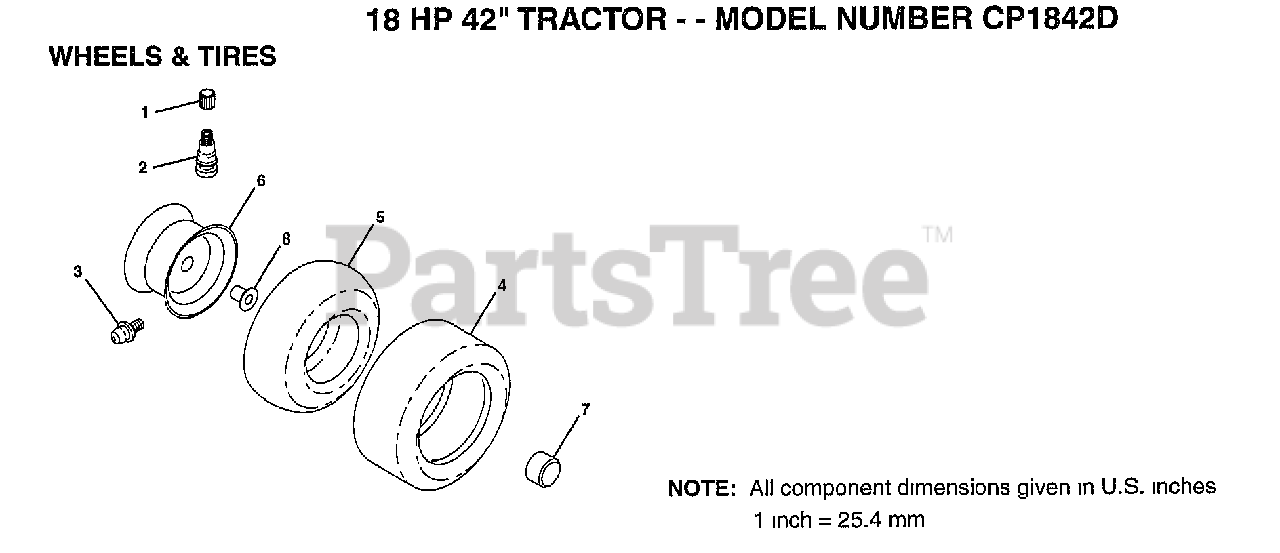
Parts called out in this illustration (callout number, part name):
1	VALVE CAP
2	VALVE STEM LT
3	FITTING LT
4	TIRE.20X8-8
5	TUBE.5.3/4.5/6
5	TUBE.18X9.5-8
6	"RIM,FRT T"
6	"RIM 8"""
7	HUB CAP
8	"FLANGE, BEARING"
